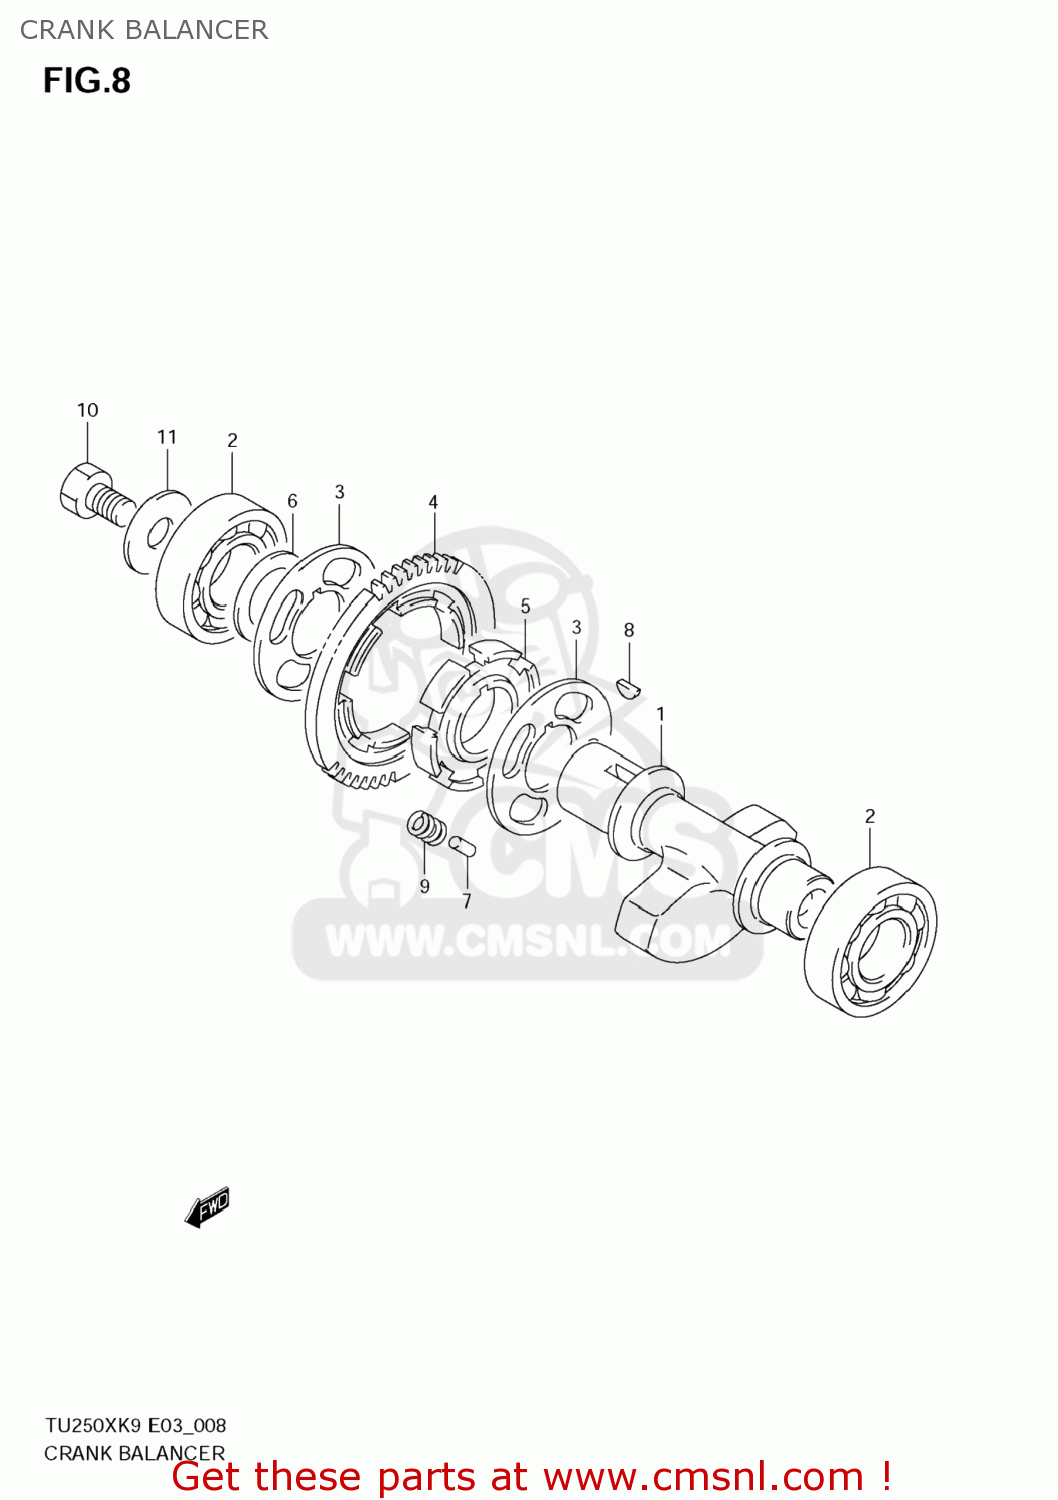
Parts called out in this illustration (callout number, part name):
1	SHAFT,CRANK BALANCER
2	BEARING(25X62X17)
3	WASHER
4	GEAR,CRANK BAL DRIVEN(NT:46)
5	RACE,CRK BAL DRIVEN GR INNER
6	SHIM(25X36X0.5)
7	PIN(4.5X9.5)
8	KEY
9	SPRING
10	BOLT
11	WASHER(12X40X2.5)
